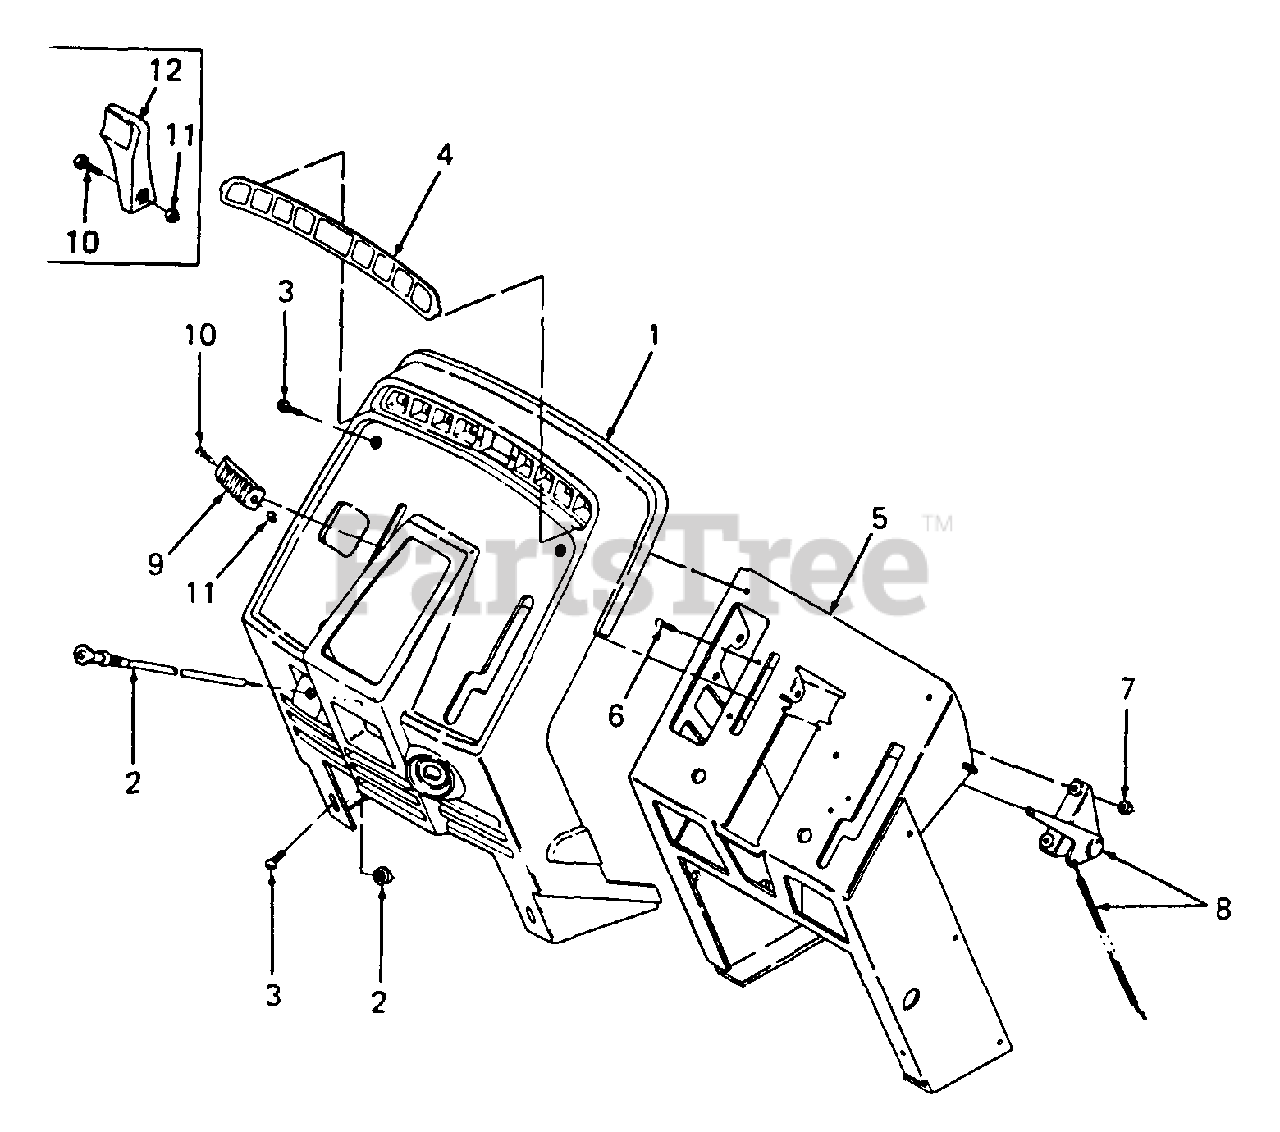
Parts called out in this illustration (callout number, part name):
1	Panel, Instrument
2	Choke Cable w/Nut
3	Screw, Pan Hd Cutting #10-24 X .75 Lg
4	Label, Dash
7	Nut, Hex Keps, #10-32
8	Control, Throttle
9	Knob, Throttle
10	Screw, Cross Rec Truss Hd #8-32 X .38 Lg
11	Nut, 8-32
12	Knob, Throttle
